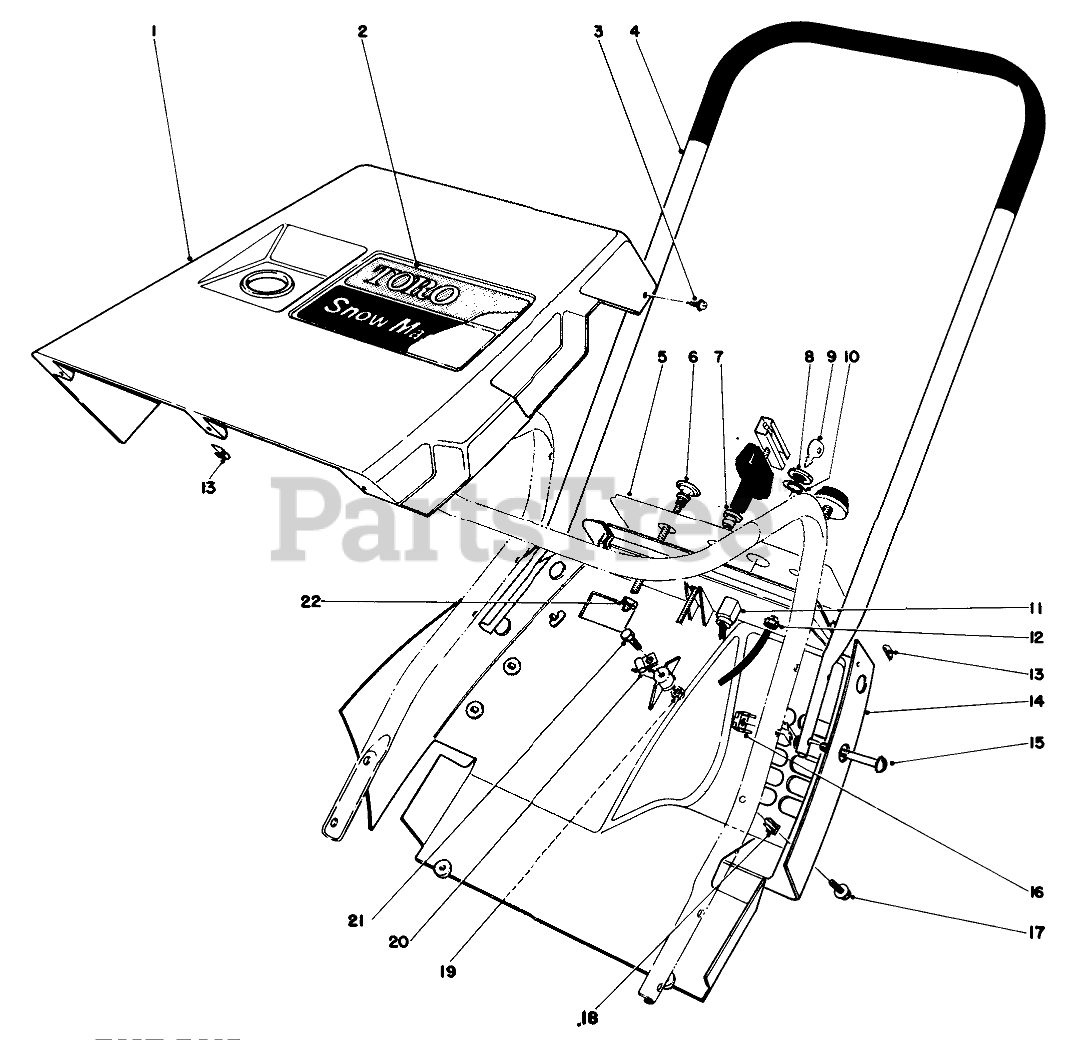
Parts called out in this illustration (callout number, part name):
1	Upper Shroud
2	Decal-Toro
3	SCREW-HWHTF
4	Upper Handle
5	Decal-Control Panel
6	Choke Cable
7	GUIDE-ROPE, STARTER
8	NUT-HH
9	Key
10	WASHER-TOOTH, INTERNAL
11	SWITCH-ON / OFF
12	NUT-KEPS
13	NUT-TYPE J
14	Lower Shroud (Incl. Ref. #5)
15	Sems Mach. Screw
16	TINNERMAN NUT
17	Screw
18	Push Nut
19	NUT-LOCK, NI
20	3/16 SUPPORT
21	SCREW-HWH
22	PAL NUT/CHOKE CNTRL
